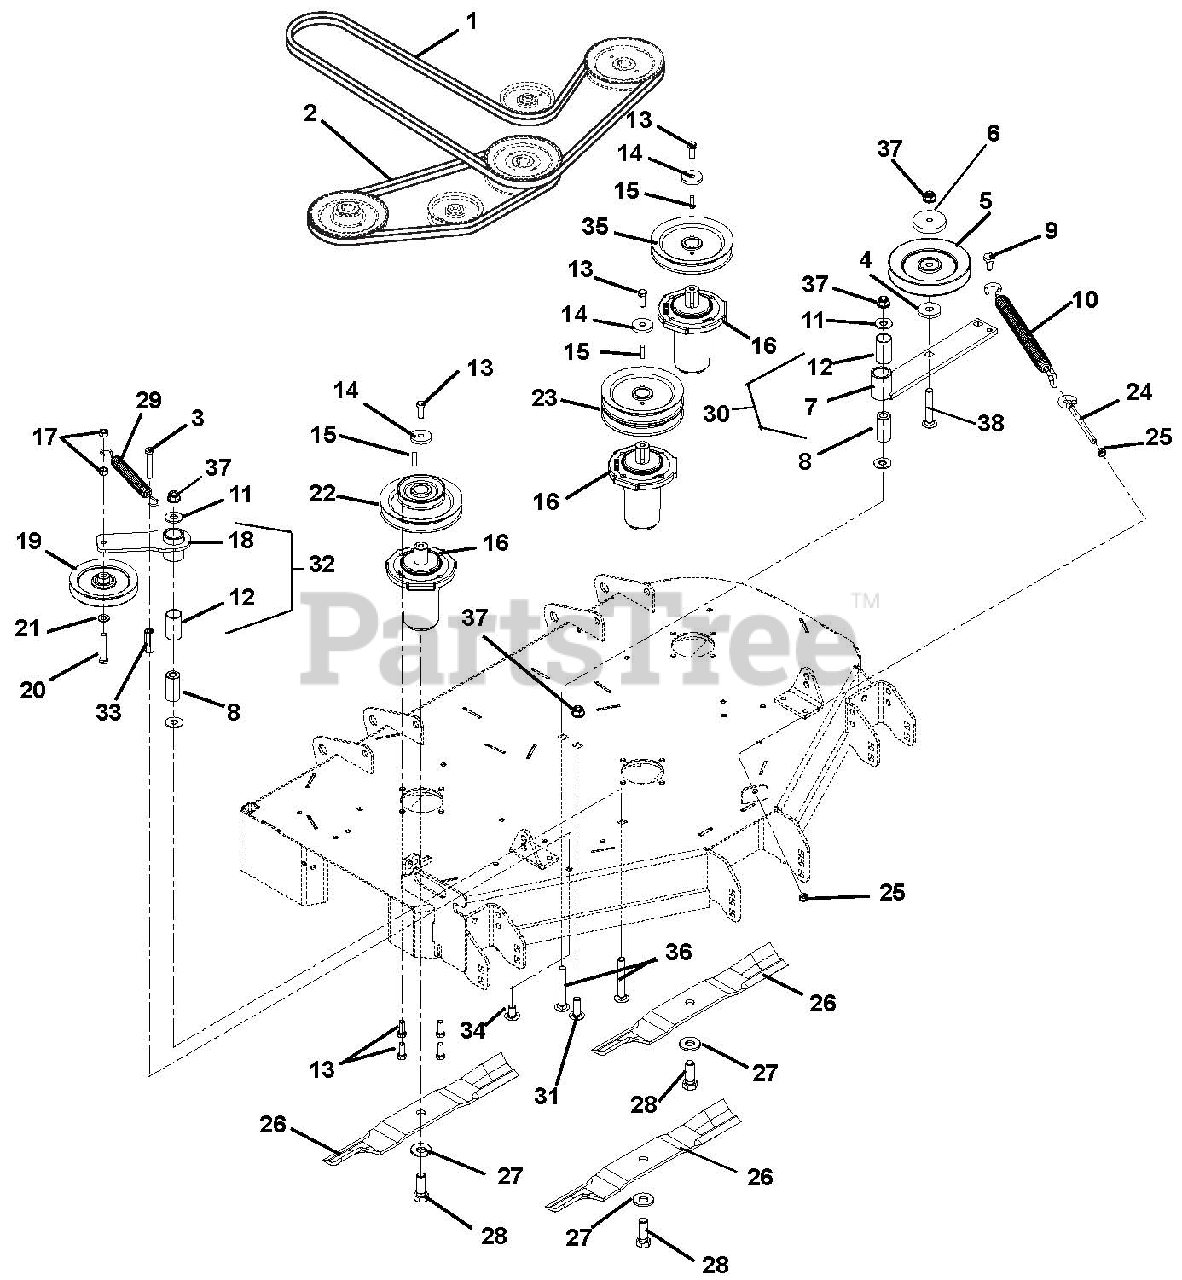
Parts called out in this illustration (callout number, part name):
1	Belt,BB 120.50 Wrapped Hex
1	Belt,BB 114.50 Wrapped Hex
2	Belt, B 51.18 RAW COGGED
3	Bolt, Hex .38-16 x 1.50 Grade 5
4	Bushing, Spacer .502 x .997 x .50 PM
5	Pulley, V 6.0 x .500 ID Single Bearing
6	Cap, Idler Bearing SEALING
7	Idler Pivot Arm Weldment- Black
8	Bearing, Pedestal
9	Bolt, Shoulder EP .38-16 x .30 Hex
10	Spring, Extension
11	Washer, Flat Steel .531x 1.250 x.100
12	Bushing, 1.00 x 1.125 x 1.936
13	Bolt, Hex .38-16 x 1.00
14	Washer, Flat Steel .406 x 1.50 x .245
15	Key, Square .25 x .25 x 1 RC 40-50
16	Spindle Assembly
17	Nut, Locking-Center .38-16
18	Idler, Pivot Arm
19	Sheave, .38" ID x 5" OD
20	Bolt, Hex .38-16 x 2.25
21	Washer, Flat Steel .406 x .812 x .065
22	Sheave, 44-48 Bagger Drive
23	Sheave, Double 1.0" ID x 5.50" OD
24	Bolt, .38-16 x 4.00 .62 Diameter Eye
25	Nut, Hex, Jam .375-16
26	Blade, 16.19" Mower
27	Washer, Bellville .63 x 1.625 x.14
28	Bolt, Hex .62-18 x 1.75 Grade 8
29	Spring, Extension
30	Assembly, PTO Idler Pivot Arm
31	Bolt, Round Head Square Neck .50-13 x 1.5, Full Thread, Grade 5
32	Assembly, Idler Pivot Arm
33	Nut, Coupling .375-16 x 1.75
34	Bolt, Round Head Square Neck .38-16 x 1.00
35	Sheave, Single 1.0" ID x 5.50" OD
36	Bolt, Round Head Square Neck .50-13 x 3.50
37	Nut .50-13 Nyloc Flange
38	Bolt, Round Head Square Neck .50-13 x 3.00 Grade 5
